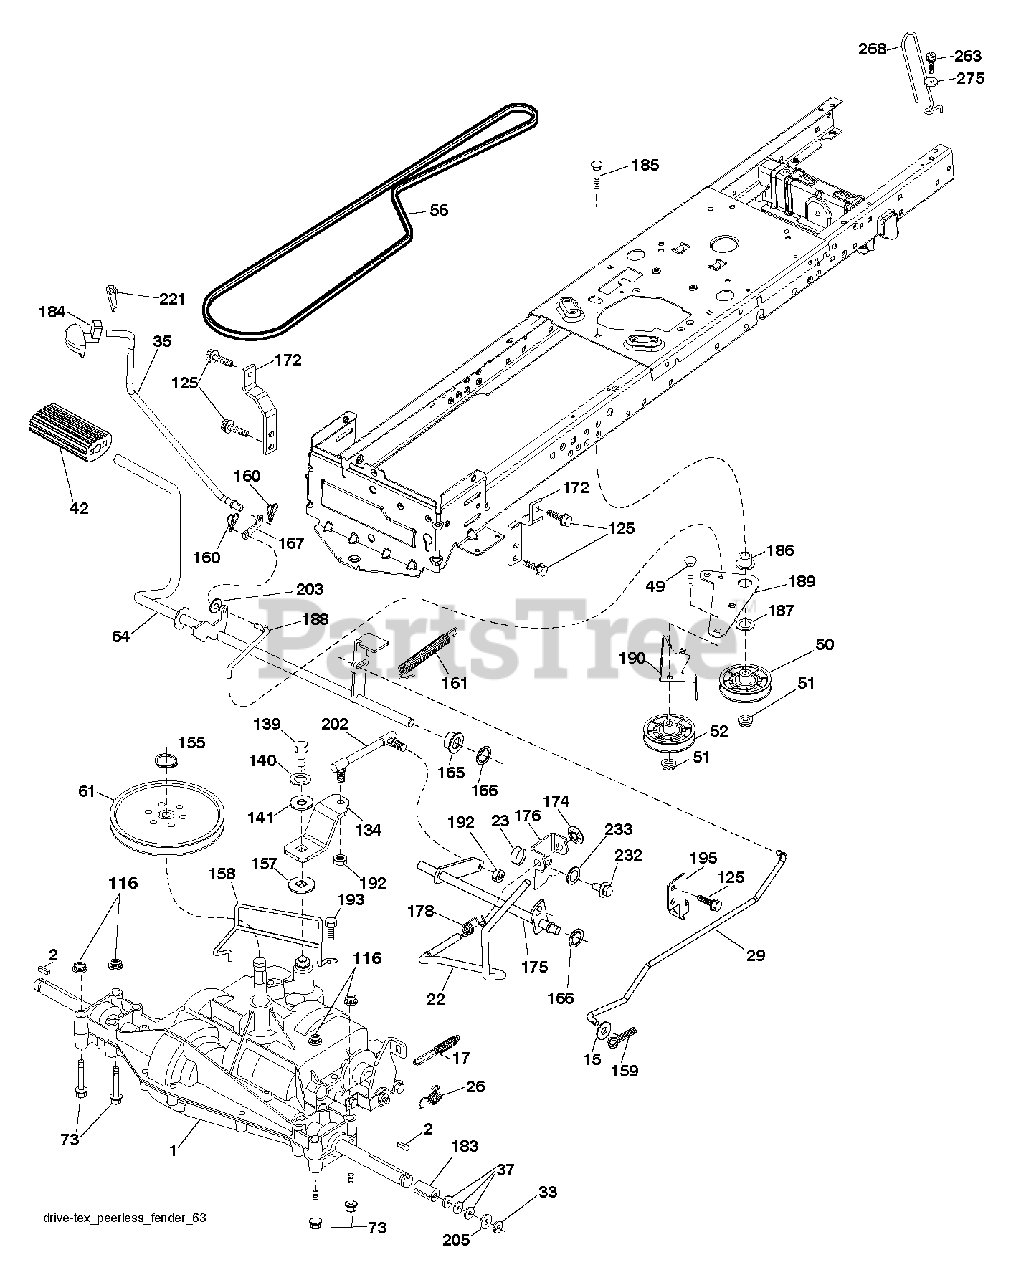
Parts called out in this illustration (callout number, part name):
2	SQUARE KEY
15	WASHER
17	SPRING.BRAKE.PEERLESS.TEX
23	KNOB.DUCKHEAD.1/2
26	SPRING.BRAKE.RTN.GR.DR
29	ROD.BRAKE.PEERLESS
35	ROD.CNTRL.PARK.PREDATOR.LT.TEX
42	PEDAL COVER T
50	IDLER.FLAT.910.OFFSET
51	NUT LOCK FLG 3/8-16 UNC
52	IDLER.V-GROOVE.910.OFFSET
56	V-BELT.TRACTOR.DRIVE.P
61	PULLEY TRANS
64	SHAFT.ASM.PEDAL.BRAKE.
116	NUT LOCK HEX FLANGE 5/16-18
125	SCREW
139	BOLT 1/4-28X3/4
140	LOCKWASHER
155	RETAINING RING LT
157	WASH-SHFT PLT LT
158	KEEPER.PMS.18/20.D4365
159	COTTER PIN
160	RETAINER CLIP
161	SPRING, RETURN LT
165	BUSHING.SHAFT.BRAKE.HAND
166	NUT.PUSH.625
167	LATCH.BRAKE.SPRING
172	STRAP.TRQ.LH.GEAR.DRIV
174	NUT.PUSH.500.2006
175	SHAFT ASM SHIFT
176	ARM.CLEVIS.ROD.SHIFT
178	SPRING.SHIFT.GT2006
183	SPACER AXLE
184	HANDLE.PARKING.BRK.PRED.LT.RED
186	SPACER.RETAINER
187	WASHER 12/32X2X10GA
188	RP LINK.CLUTCH.GROUND.DRIVE
189	BELLCRANK.GROUND.DRIVE.TEX.
190	KEEPER.BELLCRANK.DRIVE
192	NUT LOCK CENTER 1/4 -28 FNTHD
193	SCREW 5/16"
195	BRKT.ROD.BRAKE.PEERLES
202	LINK.SHIFT.PMST.18" (SPG1286)
203	WASHER
221	RETAINER.SPRING.CLIP.H
232	BOLT FIN HEX 7/16-14 X 1
233	WASHER SERRATED
263	SCREW, 3/8-16X3/4
268	GUARD MUFFLER
275	WASHER
